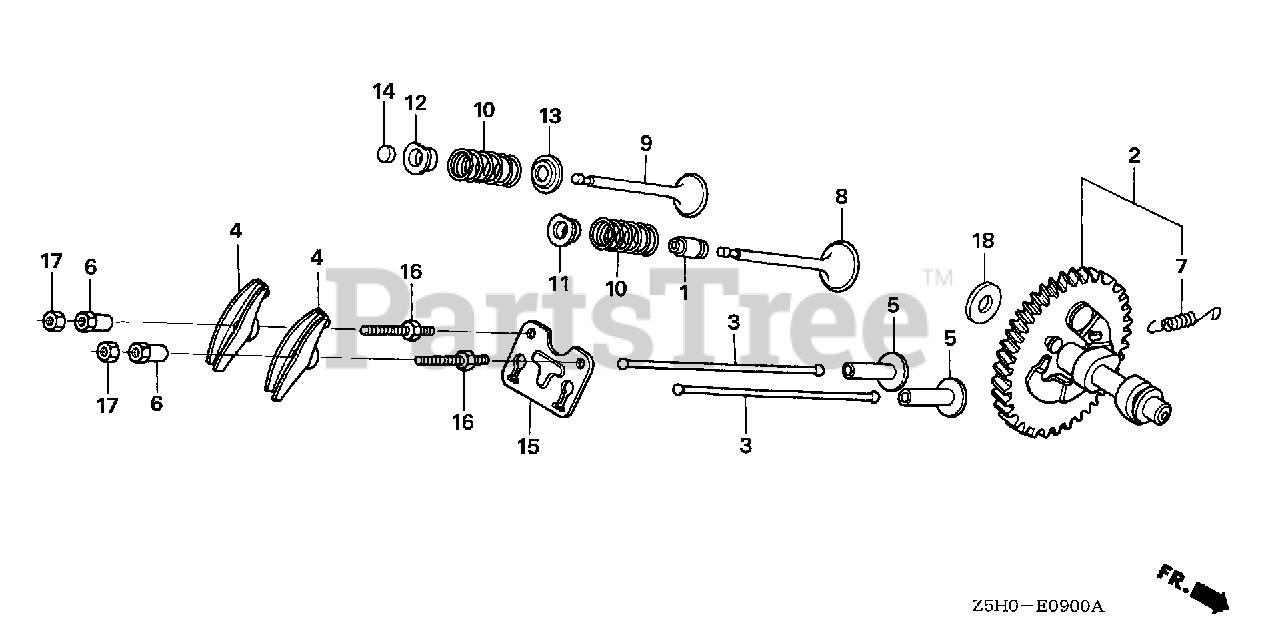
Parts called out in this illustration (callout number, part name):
1	SEAL, VALVE STEM
2	CAMSHAFT ASSY.
3	ROD, PUSH
4	ARM, VALVE ROCKER
5	LIFTER, VALVE
6	PIVOT, ROCKER ARM
7	SPRING, WEIGHT RETURN
8	VALVE, IN.
9	VALVE, EX.
10	SPRING, VALVE
11	RETAINER, IN. VALVE SPRING (EXHAUST SIDE)
12	RETAINER, EX. VALVE SPRING
13	SEAT, VALVE SPRING
14	ROTATOR, VALVE
15	PLATE, PUSH ROD GUIDE
16	BOLT, PIVOT (8MM)
17	NUT, PIVOT ADJ.
